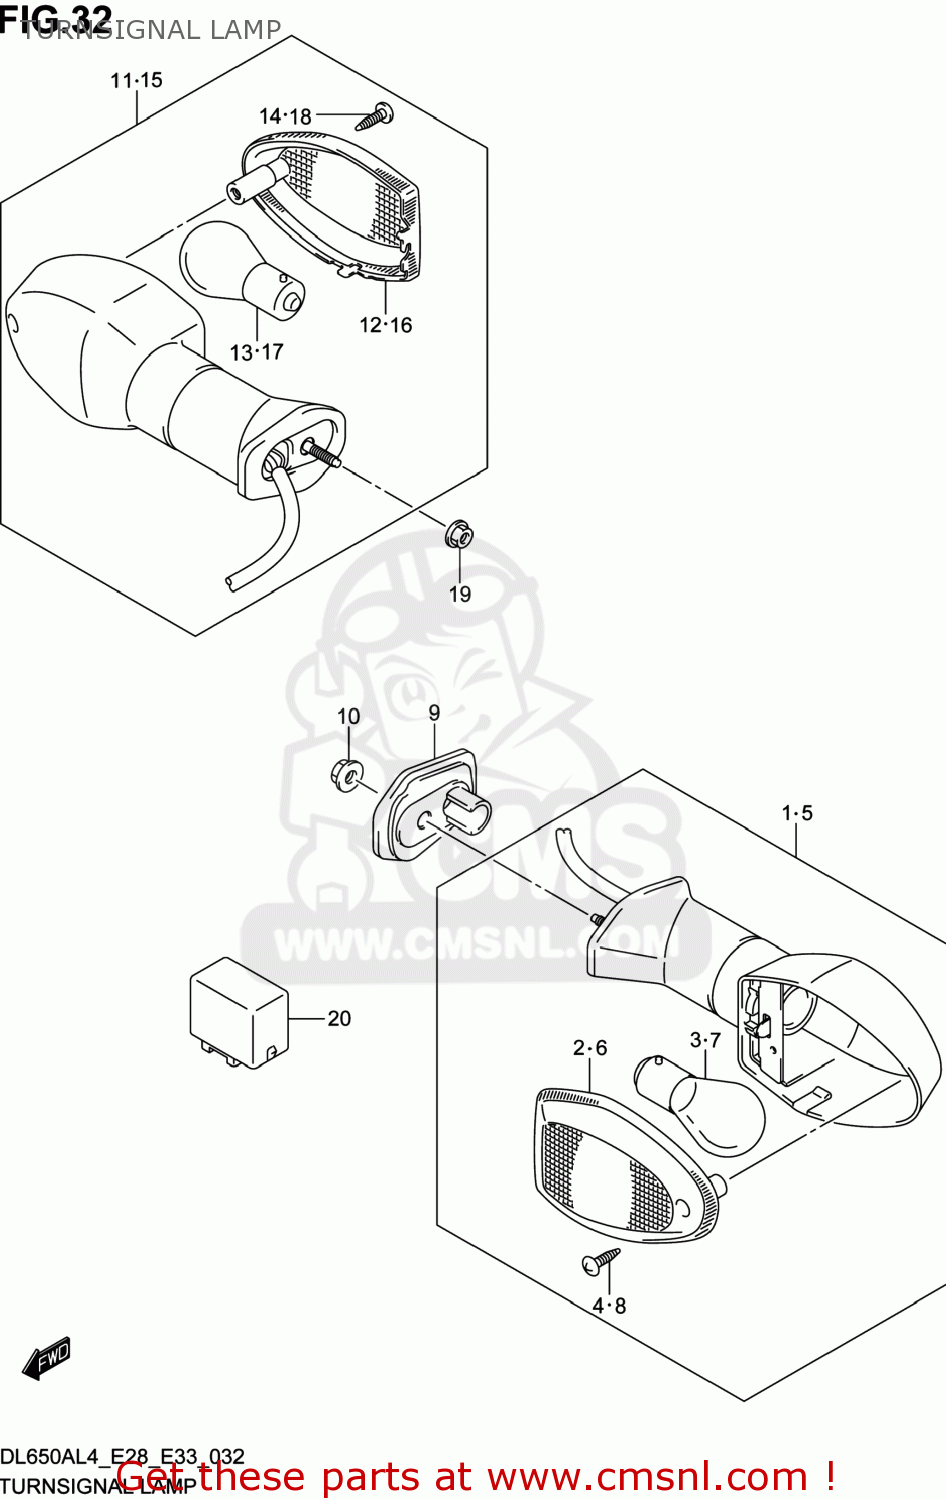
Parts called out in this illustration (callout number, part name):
1	LAMP ASSY,FRON
2	LENS,TURNSIGNA
3	BULB(12V21W)
4	SCREW
5	LAMP ASSY,FRON
6	LENS,TURNSIGNA
7	BULB(12V21W)
8	SCREW
9	PLATE,FR TURNSIGNAL
10	NUT
11	LAMP ASSY,REAR
12	LENS,TURNSIGNA
13	BULB(12V21W)
14	SCREW
15	LAMP ASSY,REAR
16	LENS,TURNSIGNA
17	BULB(12V21W)
18	SCREW
19	NUT
20	RELAY ASSY,TURNSIGNAL LAMP
